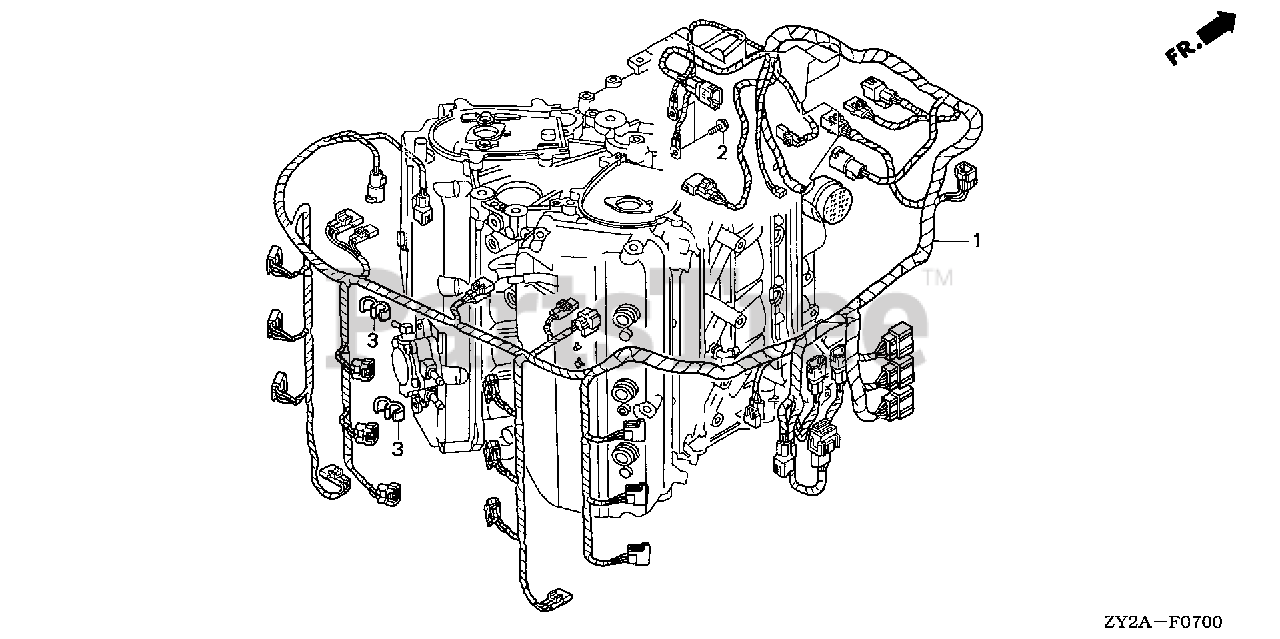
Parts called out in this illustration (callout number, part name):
1	WIRE HARNESS ASSY., MAIN
2	BOLT, FLANGE (6X12)
3	CLIP A, HARNESS
